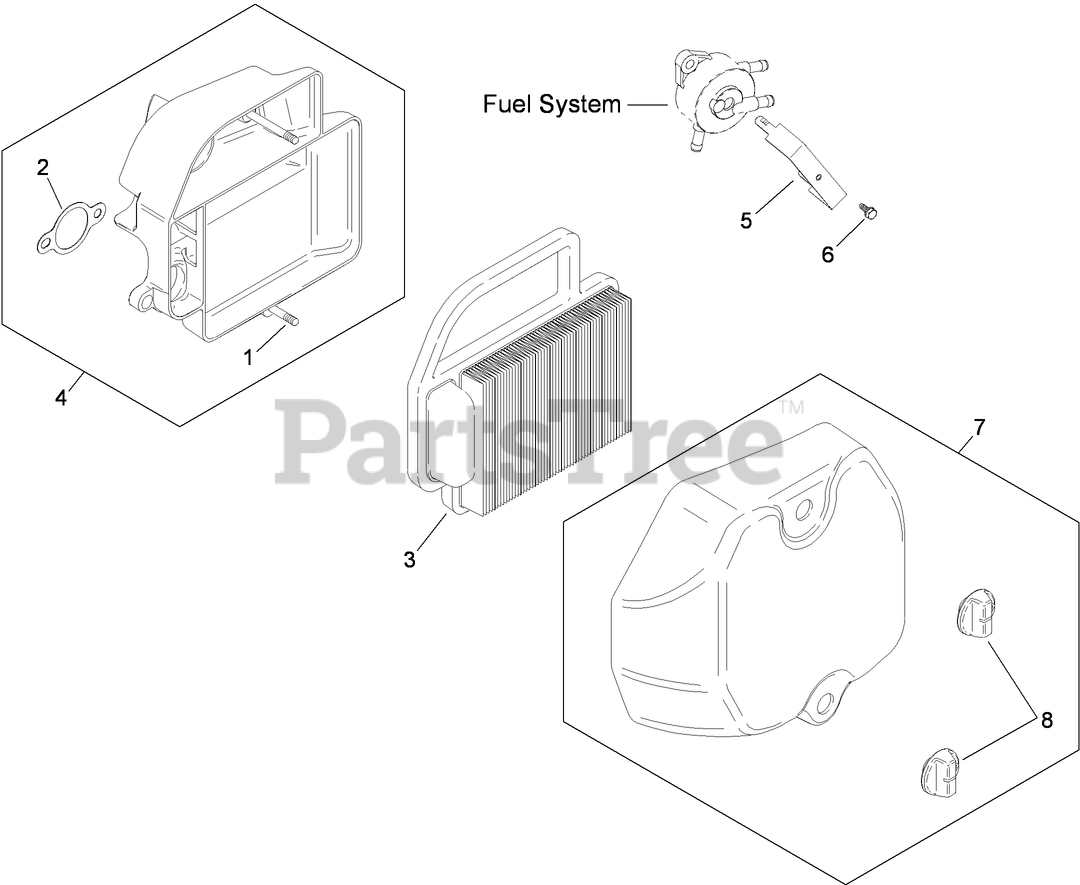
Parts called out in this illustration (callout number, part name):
1	STUD-BASE, AIR CLEANER
2	Gasket-Base, Air Cleaner
3	Element-Cleaner, Air
4	AIR CLEANER BASE ASM (INCLUDES REF 1, 2)
5	BRACKET-PUMP, FUEL
6	SCREW-THRD FRM (M4X0.7X10)
7	AIR CLEANER COVER ASM
8	KNOB-COVER
